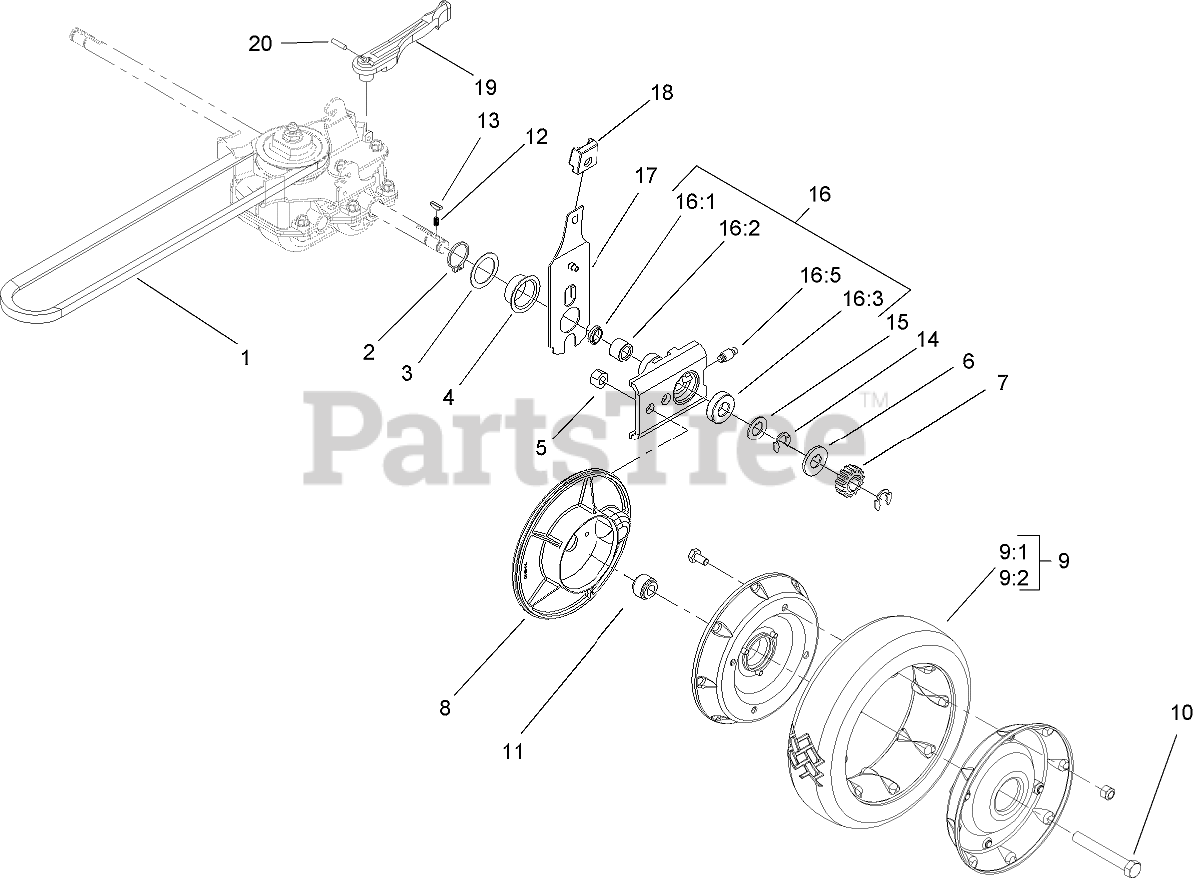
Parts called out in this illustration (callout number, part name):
1	V-BELT
2	RING-RETAINING
3	WASHER
4	CAP-END
5	NUT-LOCK, CONE
6	WASHER-THRUST, OUTER
7	GEAR-PINION
8	COVER-WHEEL
9	Wheel And Tire ASM
9:2	Wheel ASM
10	SCREW-HH
11	SPACER-COVER, WHEEL
12	SPRING-COMPRESSION
14	RING-RETAINING
15	WASHER-THRUST, OUTER
16	PIVOT ARM ASM
16:1	SEAL-OIL
16:2	BEARING-ROLLER
16:3	BEARING-WHEEL
17	REAR SPRING ARM ASM
18	KNOB-ARM
19	LEVER-SHIFT
20	PIN-COIL
